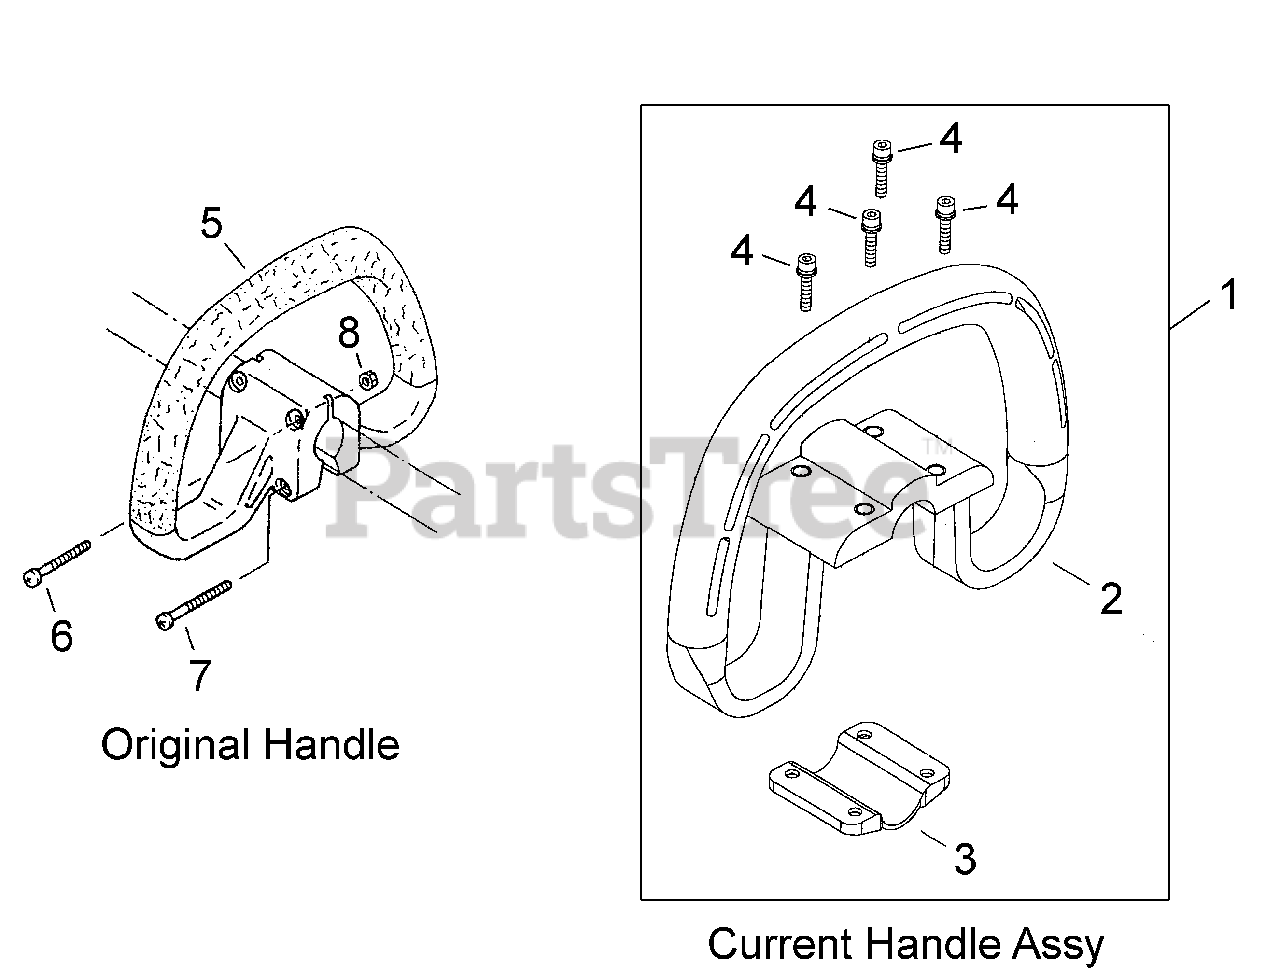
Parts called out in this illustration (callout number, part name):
2	HANDLE
3	MOUNTING BRACKET
4	SCREW - 5X25
5	HANDLE
6	SCREW - 5X30
7	SCREW - 5X45
8	NUT - 5
12-1	HANDLE ASSY
